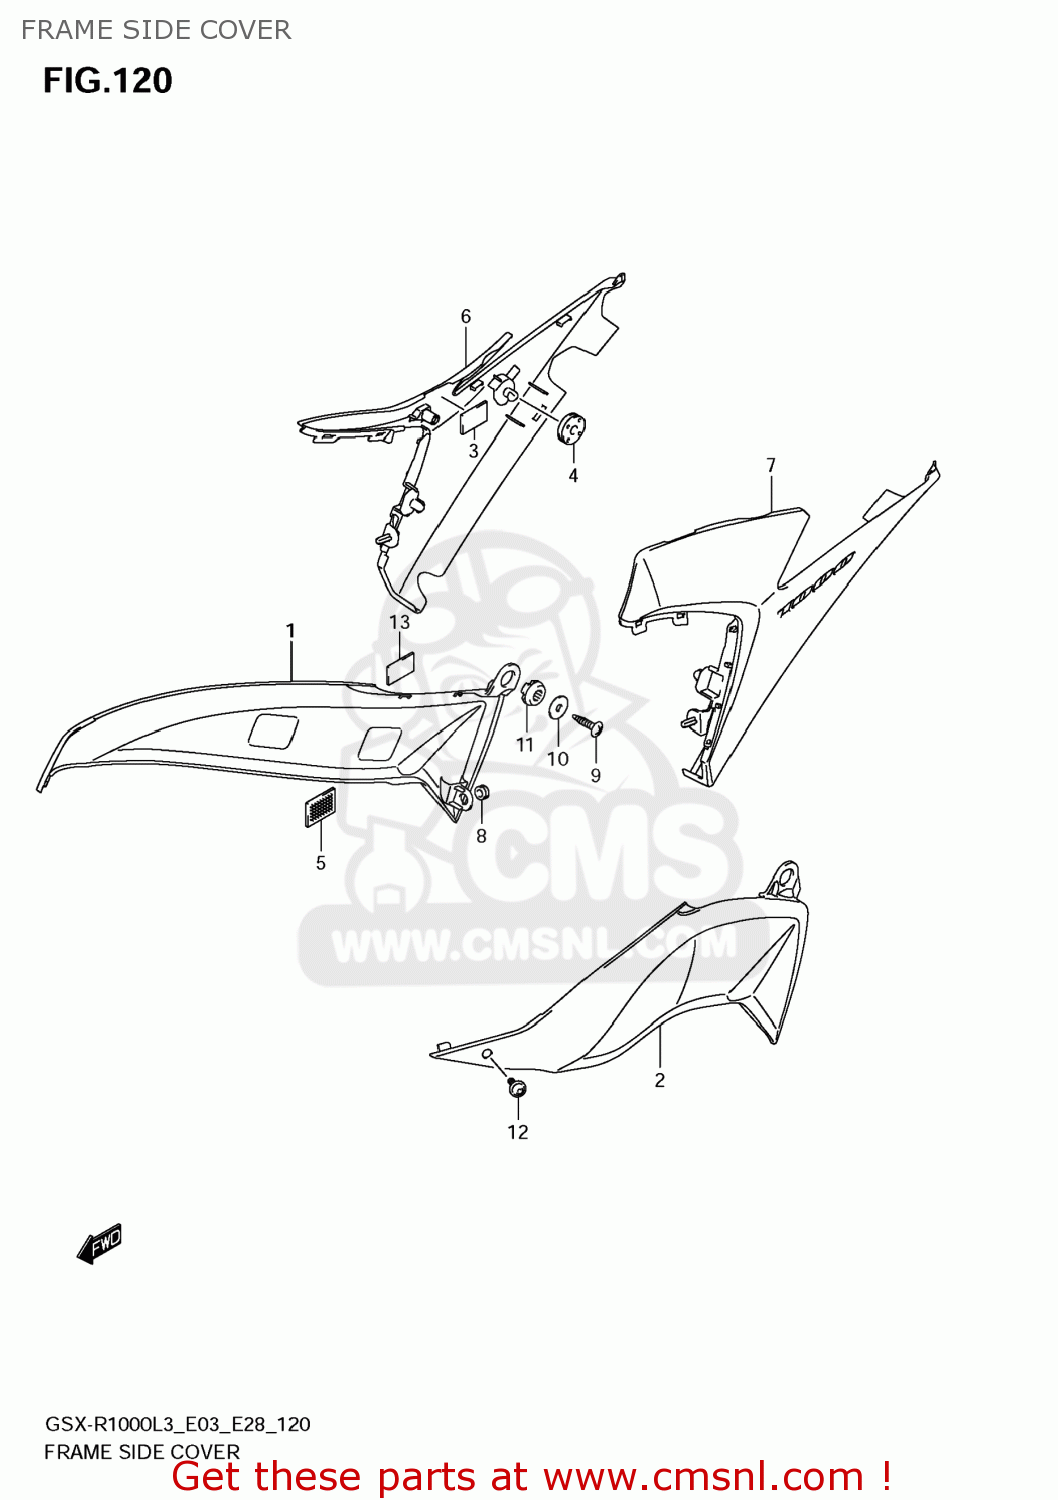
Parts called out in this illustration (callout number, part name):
1	COVER,FRAME SIDE FR,R
2	COVER,FRAME SIDE FR,L
3	CUSHION,FUEL TANK ATTACHMENT
4	CUSHION
5	FASTENER
6	COVER,FRAME SIDE,R
7	COVER,FRAME SIDE,L
8	CUSHION
9	SCREW
10	WASHER(5.5X20X1.2)
11	CUSHION
12	SCREW(5X13)
13	CUSHION(40X20X5)
